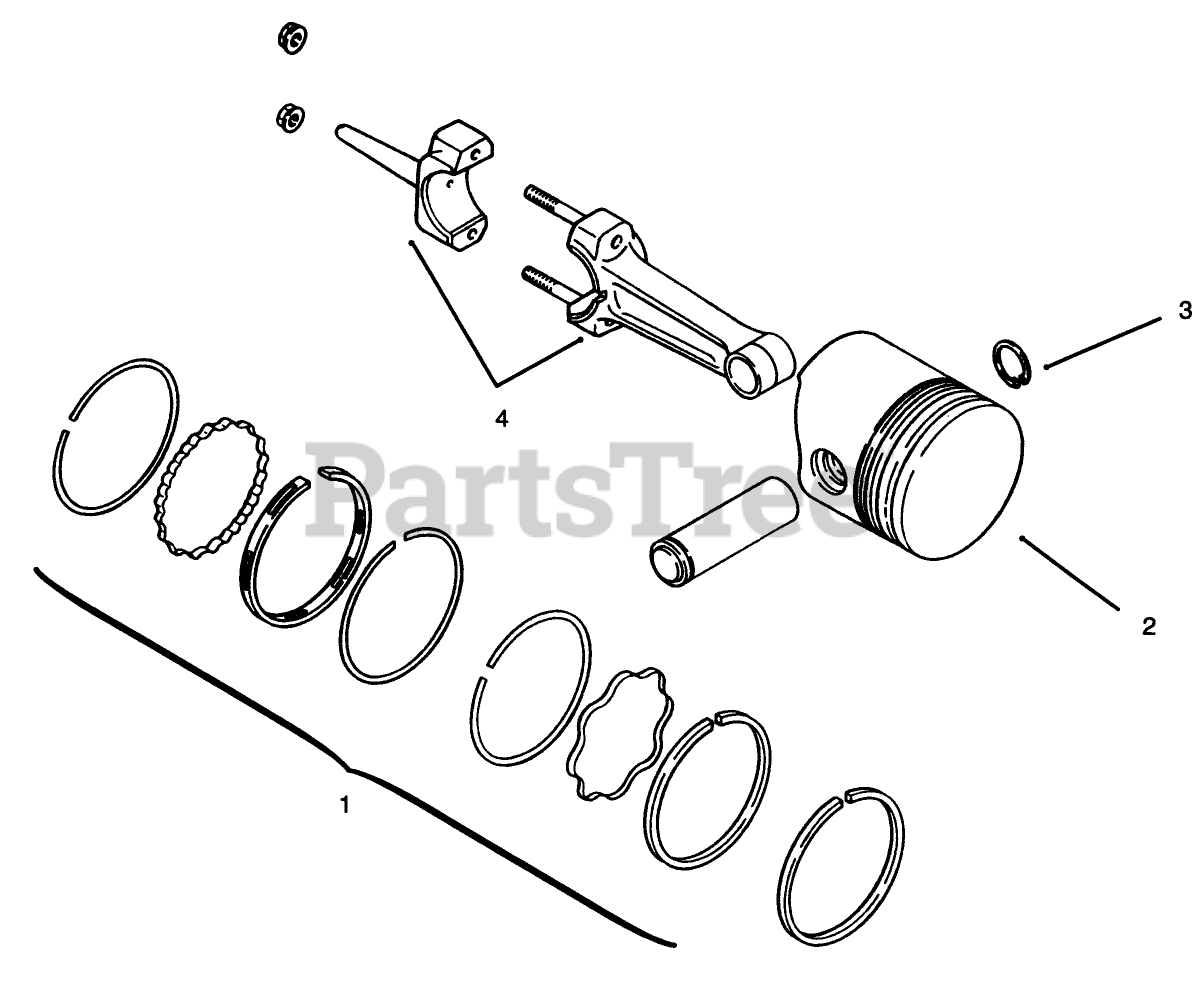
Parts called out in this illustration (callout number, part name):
1	Set-Ring STD .003 12hp
1	Set-Ring .010
1	Set-Ring .020
1	Piston-Ring Set .030
2	Piston-Ring Set .003
2	Piston-Ring Set STD 12hp
2	Piston-Ring Set .010
2	Piston-Ring Set .020
3	Retainer
4	Rod-Connecting STD
